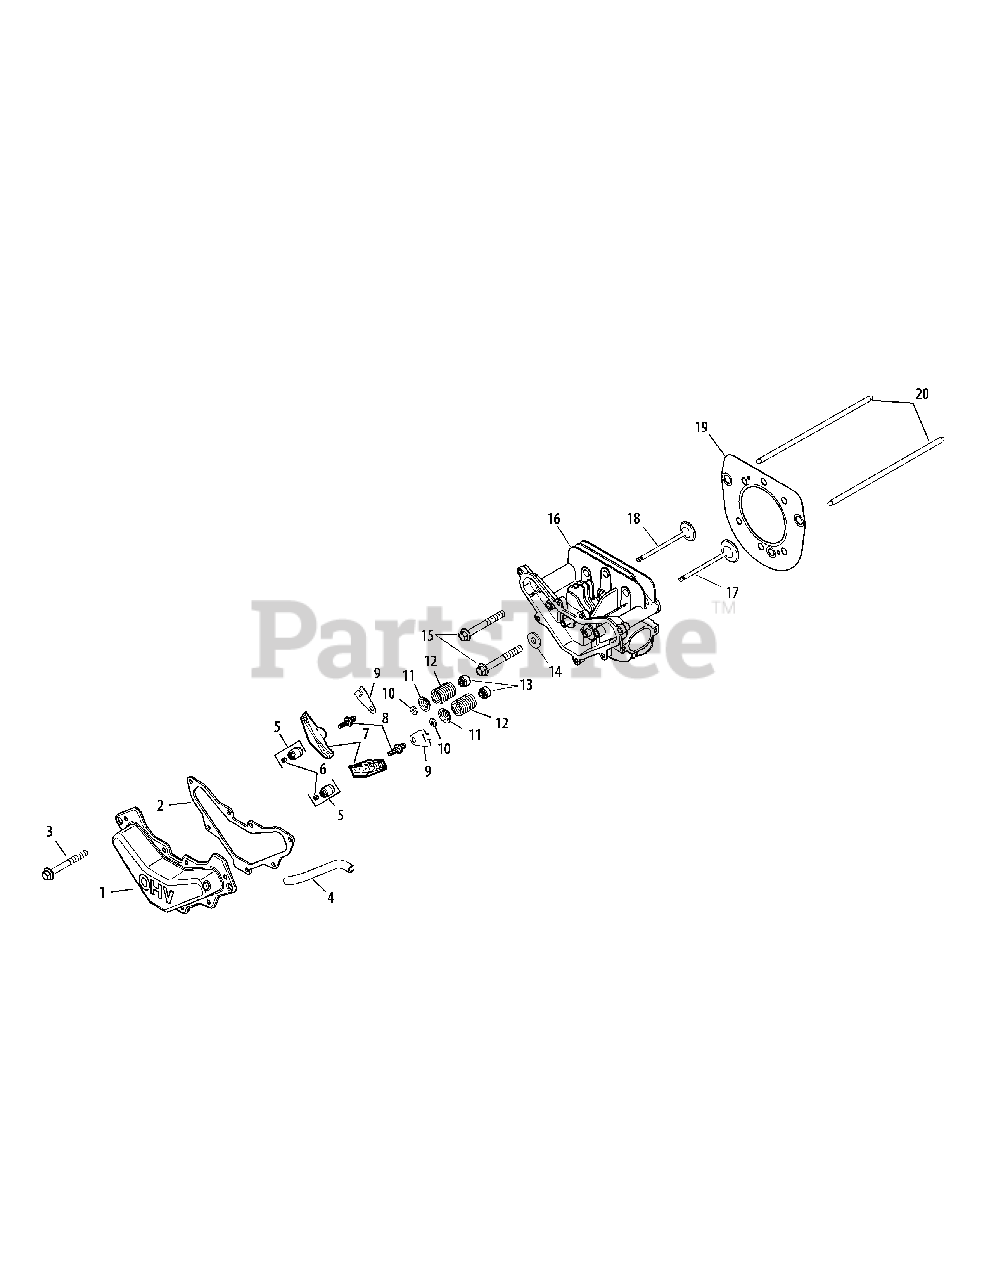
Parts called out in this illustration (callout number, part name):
1	Valve Cover Assembly
2	Valve Cover Gasket
3	Flg. Screw, M6 X 1.0 X 20
4	Breather Hose
5	Rocker Pivot Assembly (Incl. 6)
9	Push Rod Guide Plate
10	Retainer Lock
11	Valve Spring Cap
13	Valve Stem Seal
14	Flat Washer, 13/32
15	Flange Screw, M10 X 1.5 X 80
16	Kit, Cylinder Head
17	Exhaust Valve
19	Cylinder Head Gasket Kit
